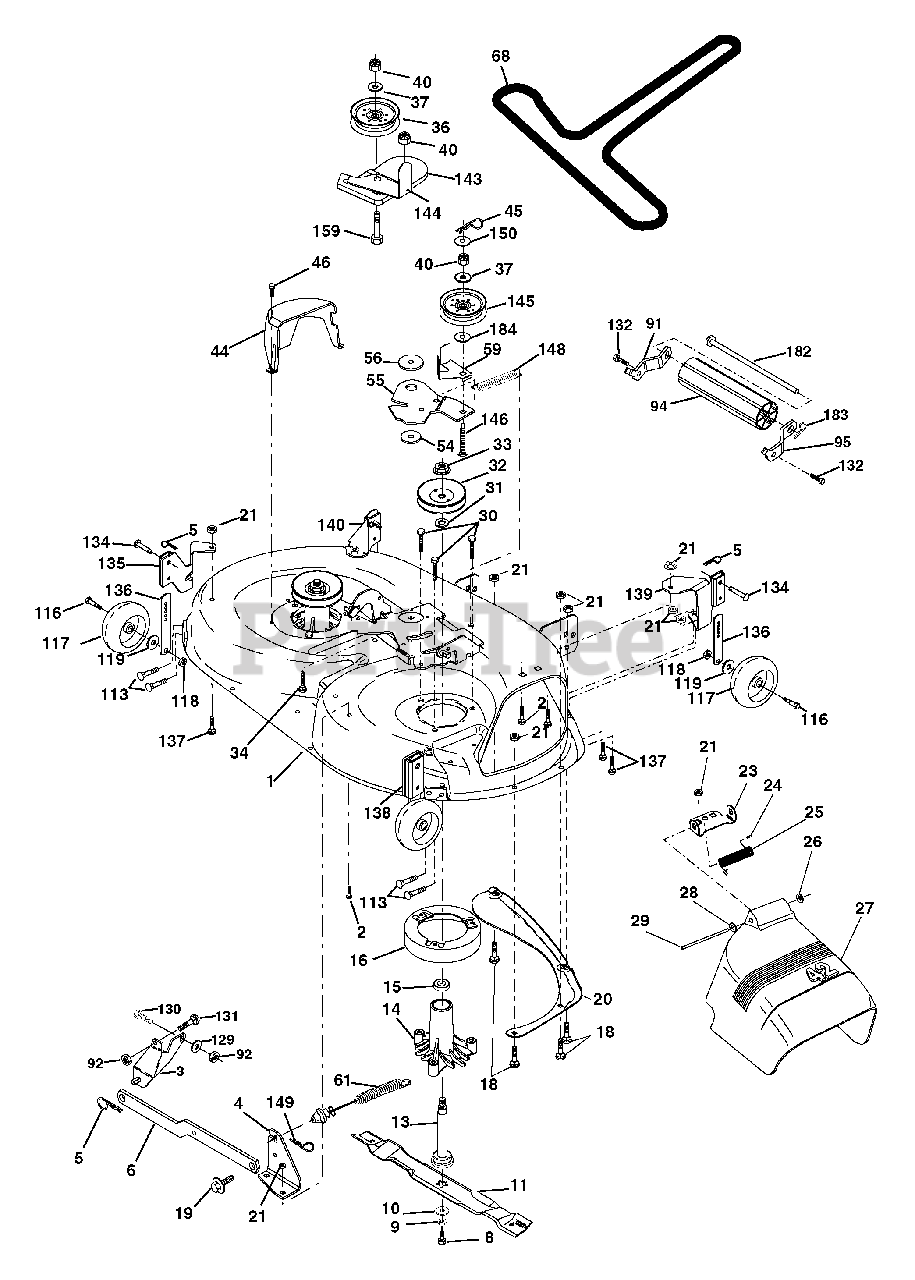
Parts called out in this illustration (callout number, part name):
1	Mower Deck Assembly, 42"
2	Bolt
3	Bracket Assembly,Sway Bar, Front
4	Bracket Sway Bar 42" Deck
5	Retainer Spring
6	Bar Sway Deck
8	Bolt, Hex 3/8-24 x 1.25 Gr. 8
9	Washer, Lock
10	Washer, Hardened
11	Blade, Mulching 42 Std
11	Blade Mulching 42 Premium
11	Blade Mower 42 Hi-Lift
13	Shaft Assembly, Mandrel, Vented
14	Housing, Mandrel, Vented
15	Bearing, Ball, Mandrel
18	Bolt, Carriage 5/16-18 x 5/8
19	Bolt, Shoulder
20	Baffle, Vortex
21	Nut Crownlock 5/16-18 UNC
23	Bracket, Deflector
24	Cap, Sleeve
25	Spring, Torsion, Deflector
27	Shield, Deflector
28	Washer 11/32 x 5/8 x 16 Ga.
29	Rod, Hinge
30	Screw Thdrol Hex
31	Washer, Spacer
32	Pulley, Mandrel
33	Nut, Toplock, Flanged
36	Pulley, Idler, Flat
37	Washer 13/32 x 13/16 x 16 Gauge
40	Nut Crownlock 3/8-16 UNC
44	Guard, Mandrel, L.H.
45	Retainer
46	Screw, Thd. Roll 1/4-20 x 5/8
54	Washer, Hardened
55	Arm, Idler
56	Spacer, Retainer
59	Guard, TUV Idler
61	Spring Ext Elect Clutch 42" Dck
91	Bracket Asm Noseroller Lh
92	Nut Lock Hex w/Ins 3/8-16 UNC
94	Roller Nose 38-50
95	Bracket Asm Noseroller Rh
113	Screw 5/16-18 x 3/4 Tap R
116	Bolt, Shoulder
117	Wheel, Gauge
118	Nut, Centerlock 3/8-16
119	Washer 3/8 x 7/8 x 14 Gauge
129	Washer 13/32 x 13/16 x Ga.
130	Bolt Fin Hex 3/8-16unc x 1 Gr.5
131	Bolt Rdhd Sqnk 3/8-16unc x 1
132	Screw 3/8-16 x .75
134	Pin Head Rivet
135	Bracket Wheel Gauge LH
136	Bar Adjusting Gauge Wheel
137	Bolt Carr. 5/16-18 x 5/8
138	Bracket wheel Gauge RH
139	Bracket Asm. Wheel Gauge F RH
140	Bracket Asm. Wheel Gauge F LH
143	Bracket Arm Idler 42"
144	Keeper Belt 42" Clutch Cable
145	Pulley Idler Flat
146	Bolt Carriage Idler
148	Spring Return Idler
149	Retainer Spring Yellow Zinc
150	Washer 9/32 x 3/4 x 16 Ga.
159	Bolt Rdhd Sqn 3/8-16 UNC x 1- 3/4
182	Rod Roller Nose
183	Retainer Spring
184	Washer 13/32 x 7/8 x 10 Ga.
